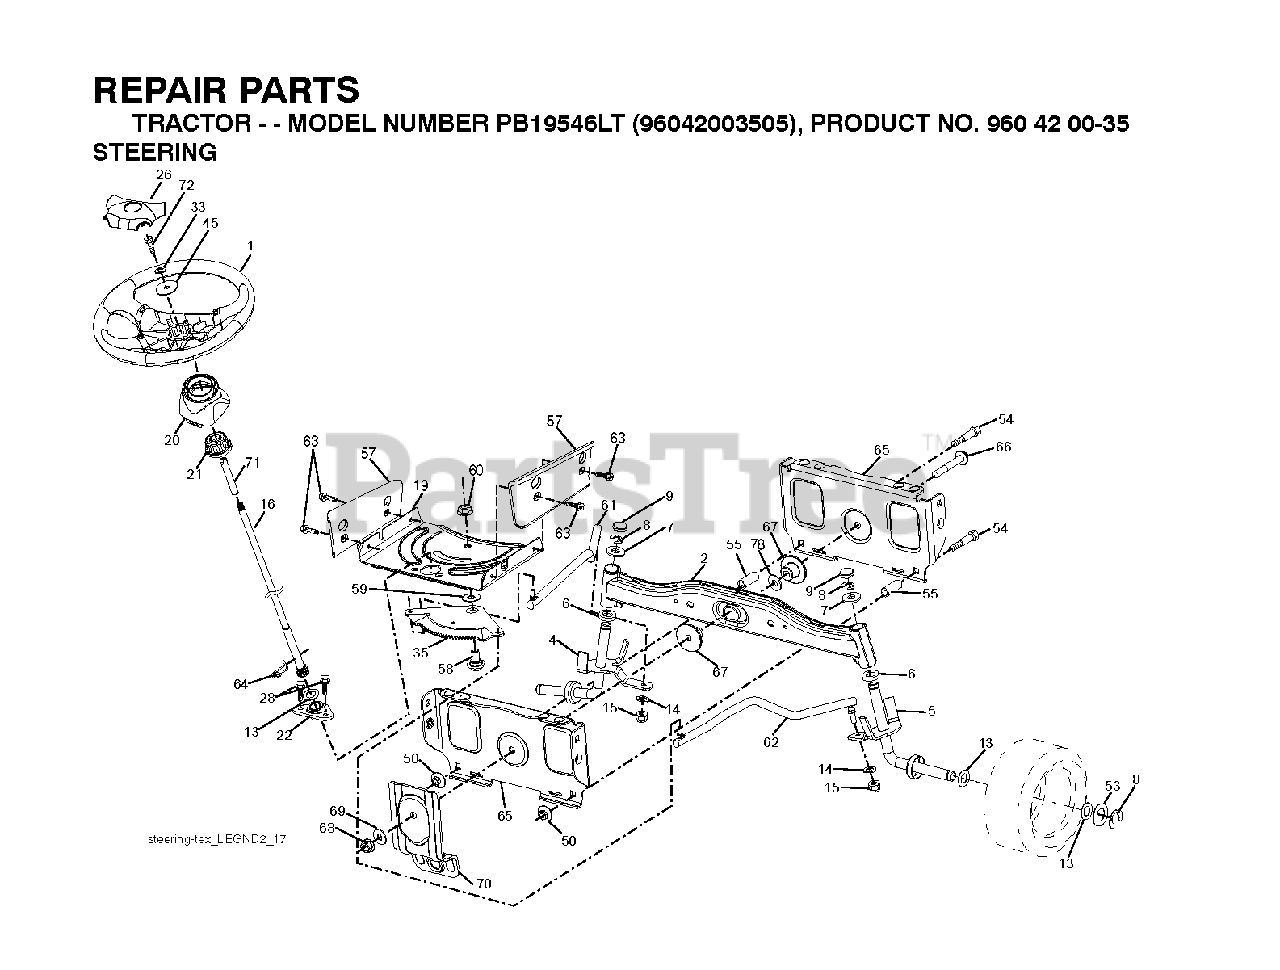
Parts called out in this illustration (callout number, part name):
1	WHEEL.STEERING.HARD.RIM.BLAC
2	AXLE HALF ASM-WELDED
4	SPINDLE.WELDED.LH.15"TEX
5	SPINDLE.WELDED.RH.15"T
8	RING CLIP
9	CAP.SPINDLE.BLACK
14	WASHER, LOCK 3/8
15	NUT CROWNLOCK 3/8-24
16	SHAFT.STEER.3/4.NON-PLATED.TEX
19	PLATE.STEER.DDL.NLT/NG
20	BOOT STEERING BLACK
21	ADAPTER, WHEEL STNG..
22	STEERING.SUPT.LOWER.
26	INSERT, WHEEL STEERING
28	SCREW, 3/8-16X3/4
33	LOCKWASHER
35	GEAR.SECTOR.PLATE.DDL.
45	WASHER.11/32
53	WASHER.HARDENED
57	BRACKET.UPSTOP.TEX
58	BOLT.SHOULDER.SECTOR.P
59	WASHER.THURST.SECTOR.S
60	NUT FLANGE LOCK 5/8-11
61	DRAGLINK.LH.BALLSTUD.D
62	DRAGLINK.RH.BALLSTUD.D
63	SCREW
64	RETAINER.CLIP.SPRING.S
66	BOLT HEX FGHD 7/16-14 X 3 SERR
67	BUSHING.PM.FRONT AXLE
68	NUT.LOCK.FLANGE.7/16
69	WASHER.1.5X.505X.118
70	BRKT.DECK.SUSPENSION.F
71	SHAFT EXTENSION STEERING
72	BOLT 5/16-18 X 4 W/PATCH
74	Steering Column Bearing
